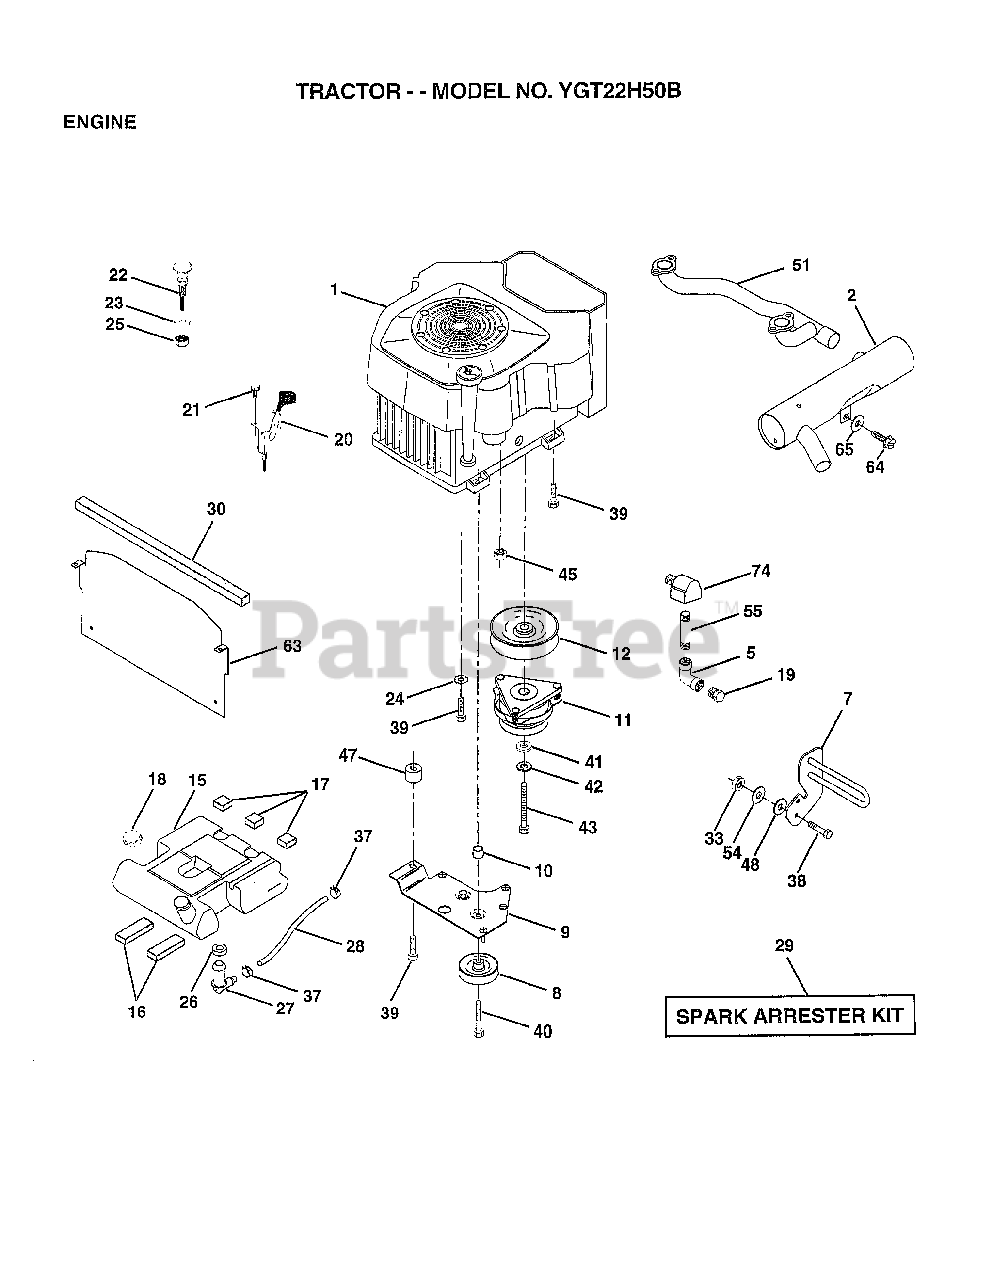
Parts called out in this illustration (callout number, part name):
2	MUFFLER SIDE1-1/8
5	ELBOW
7	GUARD.MUFFLER.ASM
9	KEEPER ASM BELT
10	BUSHING.
12	PULLEY.ENG.CLUTCH
15	TANK FUEL REAR
16	PAD IDLER TI
17	PAD-SPACER LT
18	CAP ASM FUEL
19	PLUG T
21	SCREW LT
22	CHOKE CONTROL
23	WASHER
24	LOCKWASHER
25	"NUT,KEPS 3/8-24IM"
26	BUSHING OUTLET T
27	STEM.TANK.FUEL
29	SPARK ARREST KIT
30	FOAM-STRIP LT
33	NUT
37	HOSE CLAMP
38	"BOLT,HEX"
39	SCREW.3/8-16X2.25
40	SCREW.TT.3/8-16X4
41	WASHER
42	LOCKWASHER
43	BOLT.7/16-20X4.25
45	NUT
47	SPACER.ENGINE
48	WASHER T
51	MANIFOLD PIPE VGT
54	WASHER
55	PIPE NIPPLE LT
63	HEAT.SHIELD.VGT.
65	WASHER
74	ELBOW STREET BASS
76	SCREW
